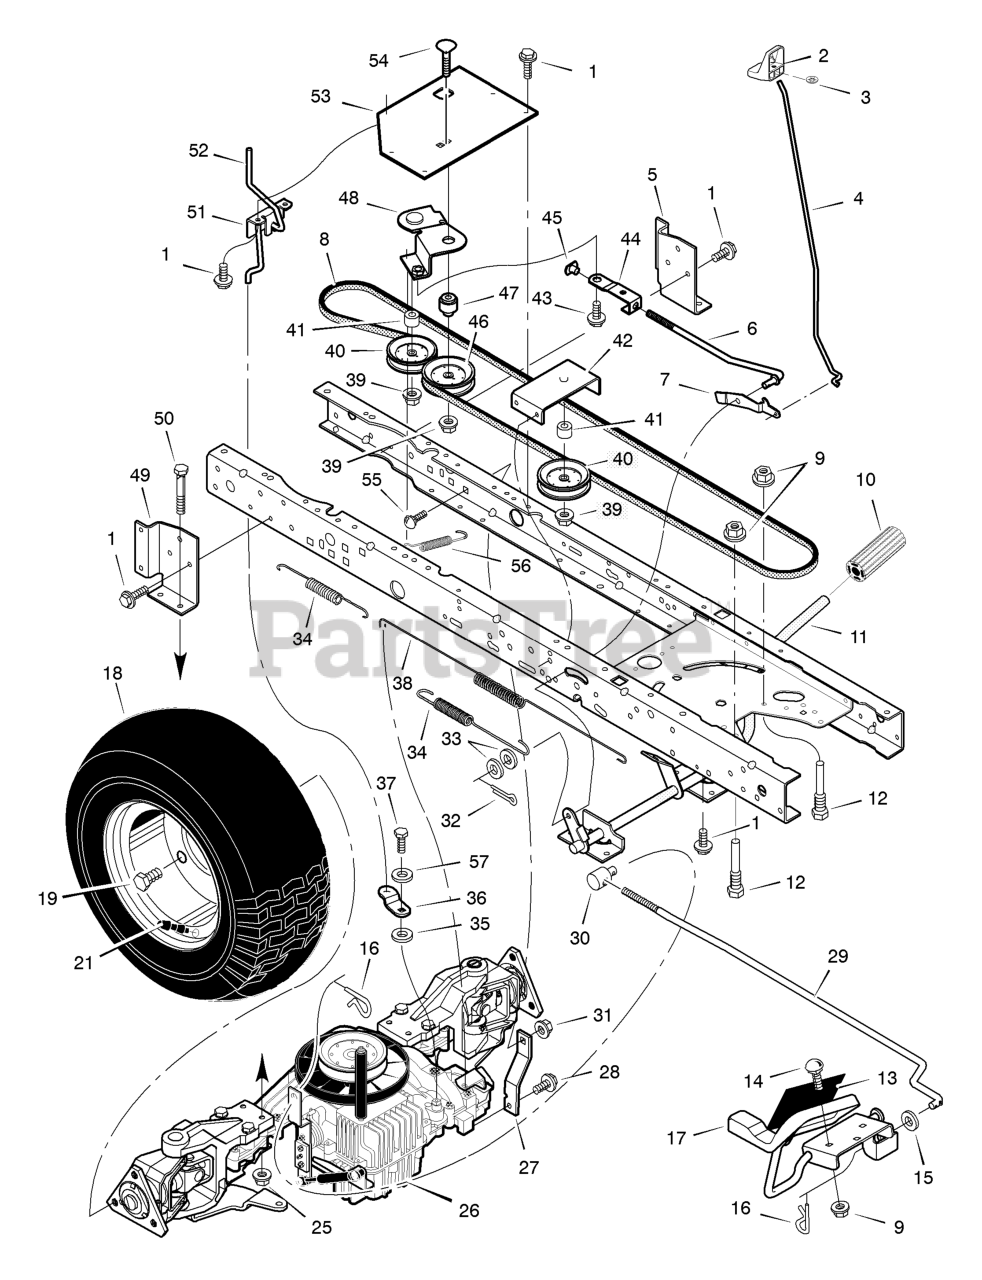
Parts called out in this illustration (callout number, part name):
2	Knob, Parking Brake
3	Nut, Push
4	Rod, Parking Brake
5	Bracket, Left Transaxle
6	Rod, Clutch
7	Latch, Parking Brake
8	V-Belt, Drive
9	Nut, Flange
10	Pedal, Brake/Clutch
11	Assembly, Brake Pedal
12	Screw, Guide
13	Pad, Pedal
14	Bolt, Carriage
16	Pin, Hair
17	Pedal Assembly, Hydro
18	Wheel & Tire Assembly
21	Stem, Valve
25	Nut, Centerlock
26	Transaxle **
27	Strap, Torque
29	Rod, Control
30	NUT, Adjusting
31	Nut, Centerlock
32	Pin, Cotter
34	Spring, Extension
36	ARM, Disconnect
37	Capscrew
38	Spring, Brake
39	Locknut, Flange
40	Pulley, Idler
42	Bracket Assembly, Idler
43	Bolt, Shoulder
44	Link, Clutch
45	Nut, Tee
46	Pulley, Idler
47	Bushing, Pivot
48	Arm Assembly, Idler
49	Bracket, Right Transaxle
51	Bracket, Disconnect
52	Rod, Disconnect
53	Bracket, Idler Pivot
54	Bolt, Carriage
55	Bolt, Carriage
56	Spring, Clutch
